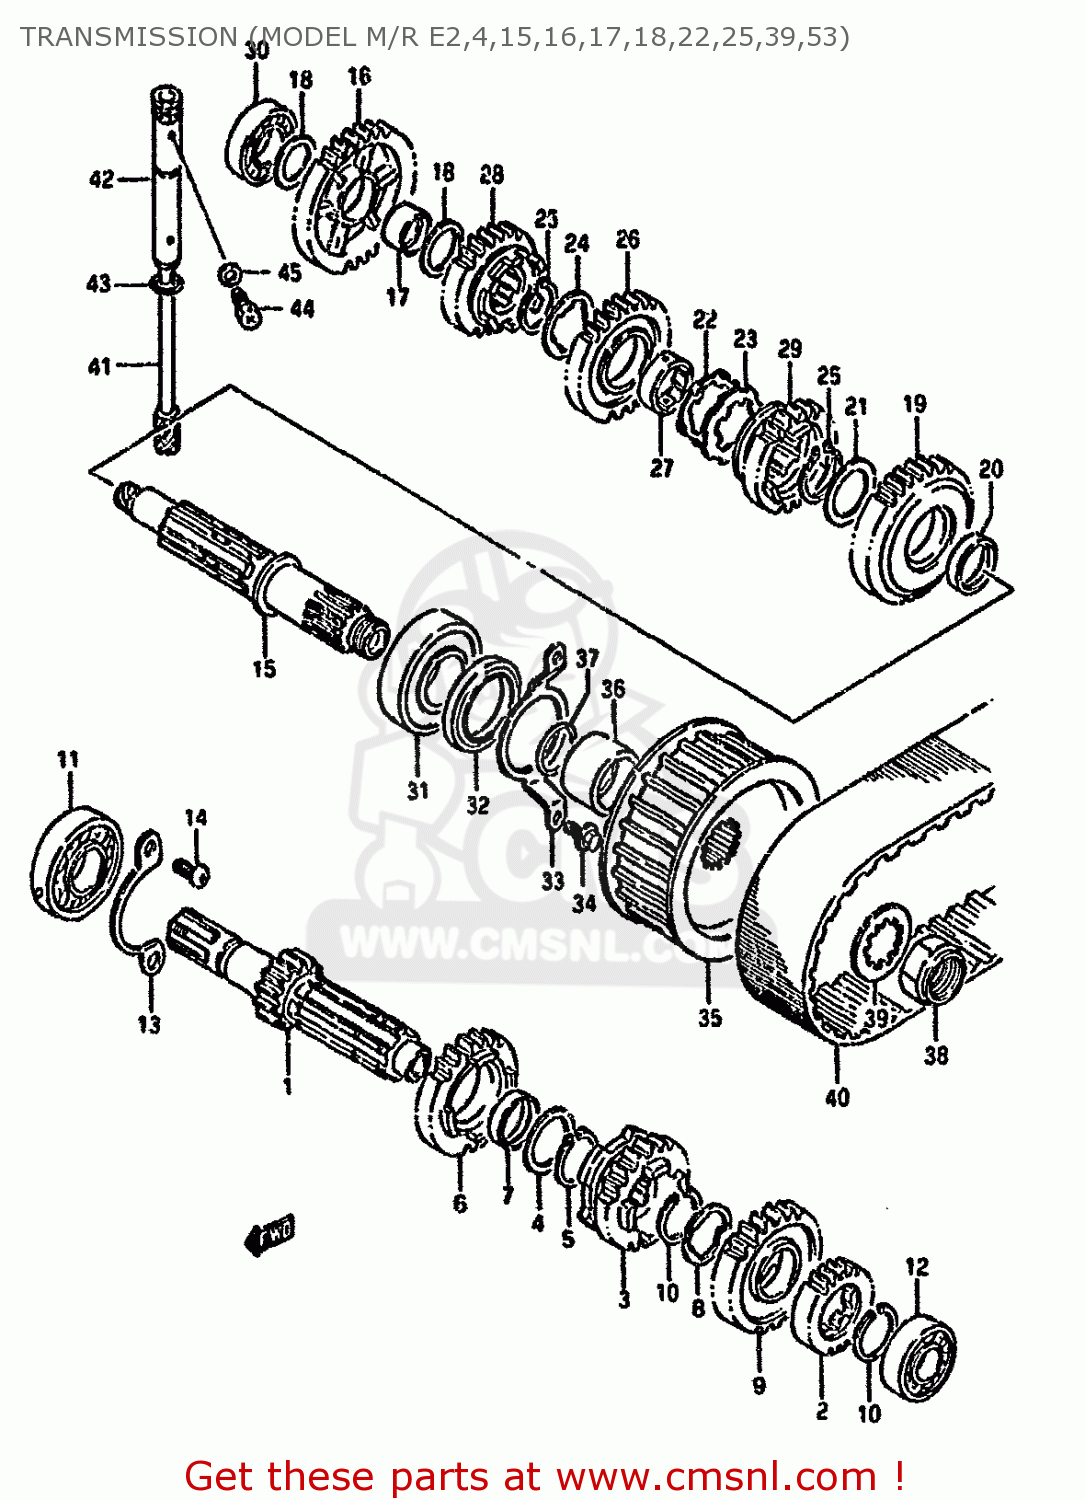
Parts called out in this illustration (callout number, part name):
1	SHAFT,COUNTER
2	GEAR,SECOND DRIVE
3	GEAR,THIRD DRIVE
4	WASHER
5	RING,SNAP
6	GEAR,4TH DRIVE
7	BUSHING 25X29X10
8	WASHER,LOCK
9	GEAR,FIFTH DRIVE
10	CIRCLIP
11	BEARING
12	BEARING(17X40X12)
13	RETAINER,CNTR SHAFT BEARING
14	SCREW
15	SHAFT COMP,DRIVE
16	GEAR,1ST DRIVEN(NT:35)
17	BUSH(20X24X13)
18	WASHER
19	GEAR,SECOND DRIVEN
20	BUSH(25X29X8)
21	WASHER
22	WASHER
23	WASHER,LOCK
24	WASHER,LOCK
25	RING,SNAP
26	GEAR,THIRD DRIVEN
27	BUSHING
28	GEAR,FOURTH DRIVEN
29	GEAR,FIFTH DRIVEN
30	BALL BEARING 20X42X12
31	BALL BEARING 25X62X17
32	SEAL,OIL(36X50X6)
33	RETAINER,DRIVE SHAFT OIL SEAL
34	BOLT
35	PULLEY,FR
36	SPACER,FR PULLEY
37	O-RING
38	NUT
39	WASHER
40	BELT,DRIVE
41	GEAR,SPEEDOMETER DRIVEN
42	SLEEVE,TACHOMETER DRIVEN GEAR
43	O RING(D:1.3,ID:9.6)
44	BOLT
45	GASKET(6.2X11X1).2 (NAS)
